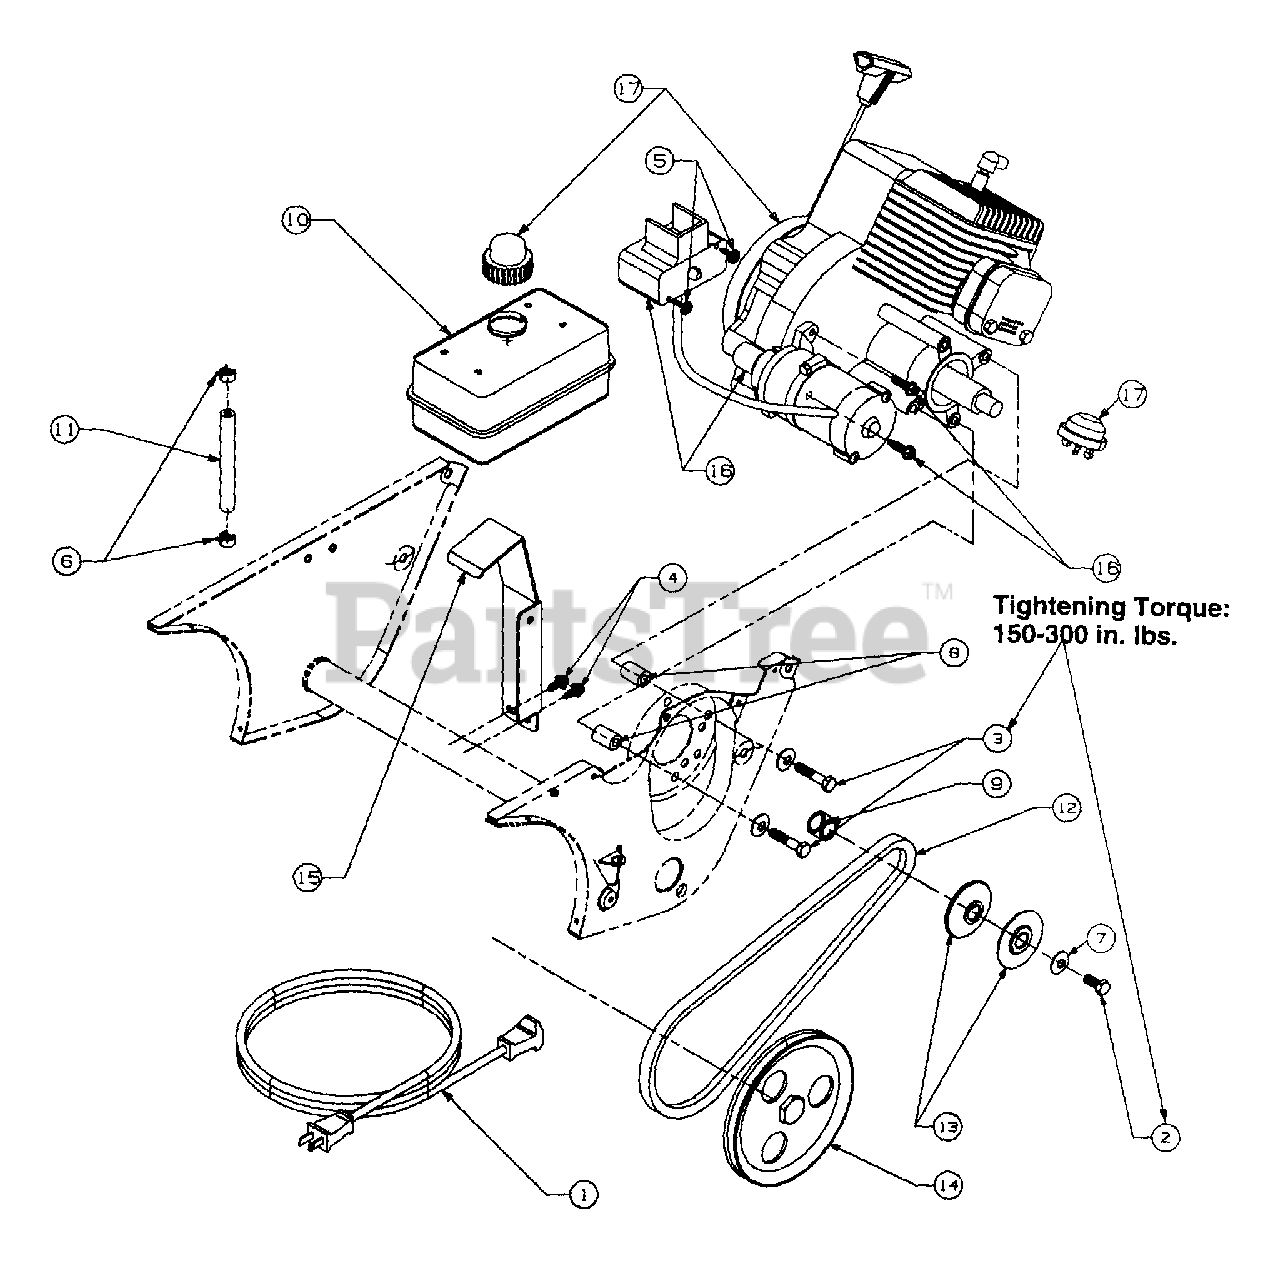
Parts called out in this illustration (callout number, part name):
1	Cord - Extension 110V3M 2 Prong
2	Screw - Hex Cap
3	Screw - Hex Cap
4	Screw - Washer
5	Screw - Hex
6	Hose Clamp
7	Washer - Bell
8	Spacer
9	Spacer
10	Tank - Fuel 1 Qt.
11	Hose - Fuel 12"
12	V-Belt
13	V-Pulley Half
14	Pulley
17	Engine
